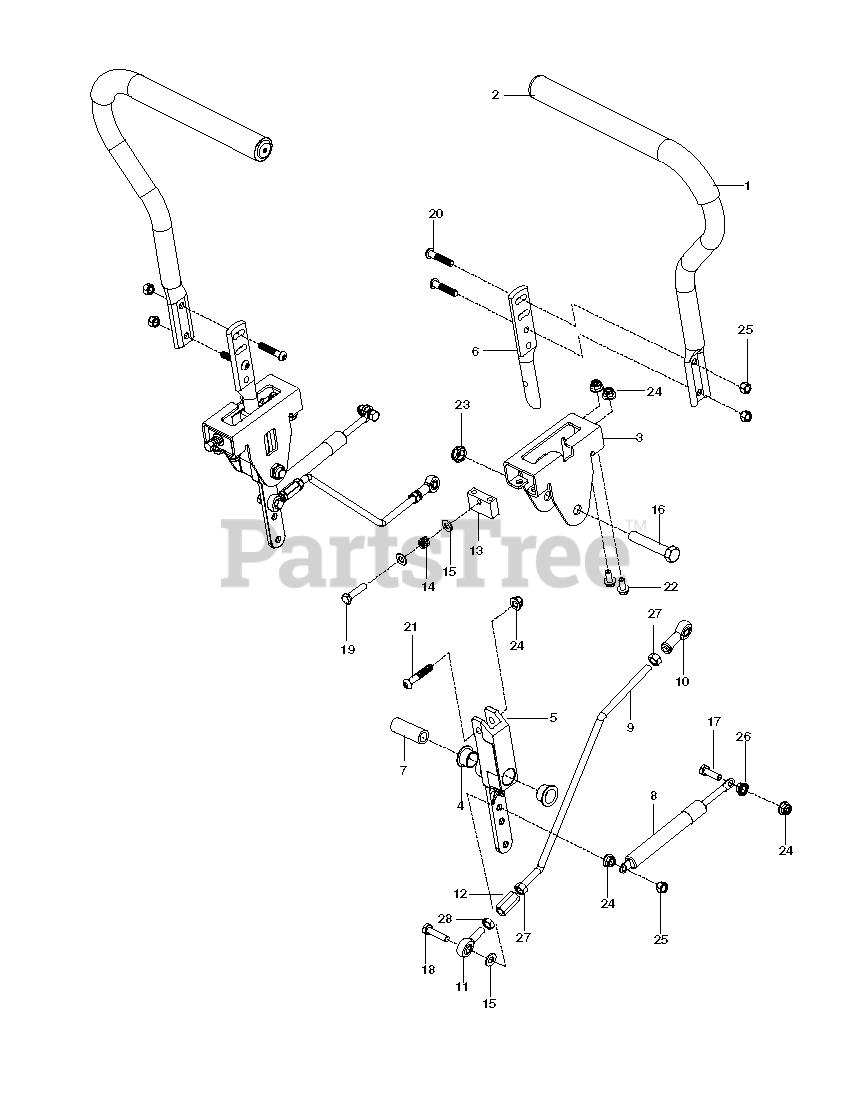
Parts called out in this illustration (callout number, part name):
1	LEVER ASM
2	GRIP, DRIVE LEVER
3	BRACKET, CONTROL
4	BEARING, FLANGE
5	LEVER CONTROL PIVOT
7	SPACER, PIVOT CONTROL
8	DAMPENER
10	RH ROD END
11	ROD END LH
12	ROD END COUPLER
13	BLOCK, TRACKING
15	FLAT WASHER 5/16 SAE
16	HCS 1/2C X 2 3/4
17	HCS 5/16C X 1
18	HCS 5/16-18X1-3/4 TPBLT
19	CAPSCREW 5/16 X 1/1/2 HEX HEAD
20	SCREW 5/16-18 X 1 BTN-HD
22	HHFS 5/16-18 X 3/4
23	NUT 1/2-13 HEX JM NYL
24	5/16-18 NYLOC FLANGE NUT
25	NUT 5/16 NYLOC
26	NUT 5/16C WHIZ
27	NUT 5/16F
28	NUT 5/16F LEFTHAND
